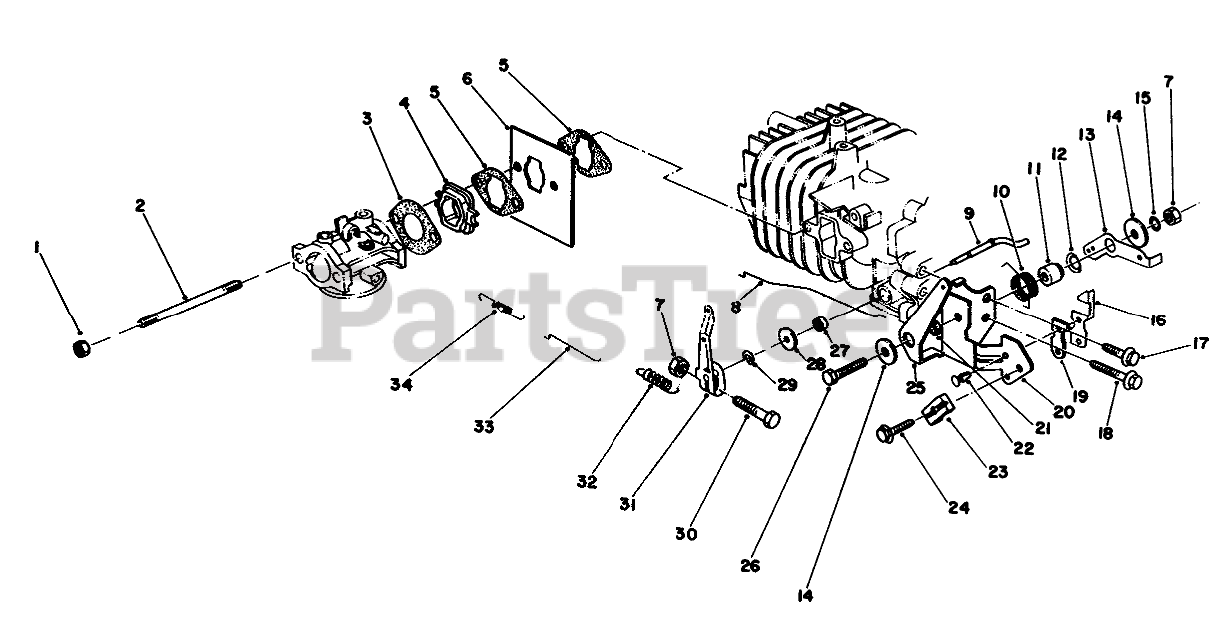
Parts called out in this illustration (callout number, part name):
1	NUT-LOCK
2	CARB STUD BOLT
3	Clamp
4	INSULATOR
5	GASKET
6	SHIELD
8	CHOKE ROD
9	VALVE GUIDE REAMER
10	Spring-Choke Control Lever
11	Gov Lever Spacer
12	Washer-Gov. Spring Lever
13	GOV SPRING LEVER
14	MAIN JET
15	LOCKWASHER
16	TERMINAL-KILL SWITCH
18	E-RING
19	INSULATOR-KILL SWITCH
20	Bracket-Throttle Control
21	Spacer-Choke Control Lever
22	KILL SWITCH RIVET
23	CLAMP-CABLE
24	Brush
25	LEVER-CONTROL, CHOKE
27	Oil Seal-Governor Shaft
28	WASHER
29	E-RING
31	VALVE GUIDE REAMER/INST
32	GOVERNOR SPRING
33	ROD-CARBURETOR
34	SPRING
